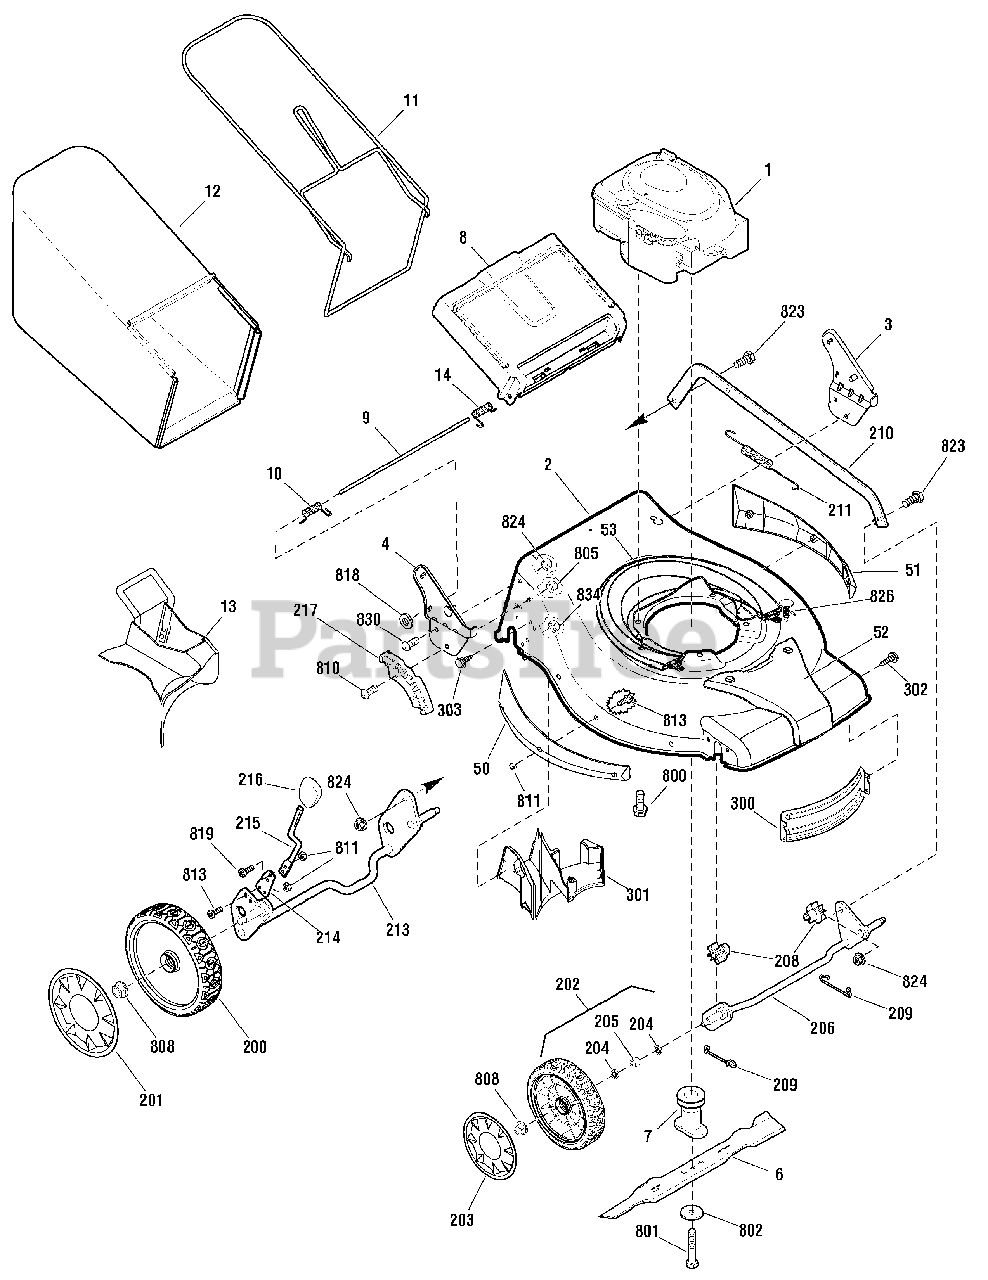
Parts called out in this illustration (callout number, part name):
1	* ENGINE, B&S 675 Series, EU
1	* ENGINE, B&S 700 Series DOV, EU
2	MOWER HOUSING
3	BRACKET ASSEMBLY, Left Handle
4	BRACKET ASSEMBLY, Right Handle
6	BLADE, 19"
7	BLADE ADAPTER ASSEMBLY
8	DOOR, Rear
9	ROD, Rear Door
10	SPRING, Torsion Rear Door, Right
11	FRAME ASSEMBLY
12	BAG ASSEMBLY
13	MULCH PLUG
14	SPRING, Torsion Rear Door, Left
50	SIDE GUARD, Right
51	SIDE GUARD, Left
52	HOUSING COVER, Front
53	HOUSING COVER, Rear
200	WHEEL, Rear
201	HUBCAP, Rear
202	WHEEL ASSEMBLY, Front, Ball Bearing 175MM Tread III SL
203	HUBCAP, Front
204	WHEEL BEARING (Not Available)
205	SPACER (Not Available)
206	CROSSBAR ASSEMBLY, Front
208	BUSHING, Front Crossbar
209	SPRING, Clip Crossbar
210	LINK, Single Lever
211	SPRING, Extension
213	REAR CROSSBAR
214	SPRING, Adjuster
215	LEVER, Height Adjustment
216	KNOB, Adjuster
217	BRACKET, Height Adjuster
300	BAFFLE, Front
301	BAFFLE, Rear
302	SCREW, 1/4-20 x 1/2
303	SCREW, Hi-Lo, Pan Head Torx, 1/4-15 x 5/8
800	SCREW, Hex Head, 3/8-16 x 1
801	BOLT, Blade, 3/8-24 x 2
802	WASHER, Belleville
805	NUT, Nylock, M8 x 1-1/4
808	NUT, Flange, 3/8-16
810	BOLT, Hex Key Head
811	NUT, Nylock
813	SCREW, Torx Head, M5 x .8 x 14mm
818	PUSHNUT, 1/4
819	SCREW, Torx Head, M5 x .8 x 12.5mm
823	BOLT, Shoulder, 5/16-18 x 1
824	NUT, Flange, 5/16-18
826	SCREW, 1/4-20 x 7/8
830	SCREW , 5/16-18 x 3/4
1000	DECAL KIT
